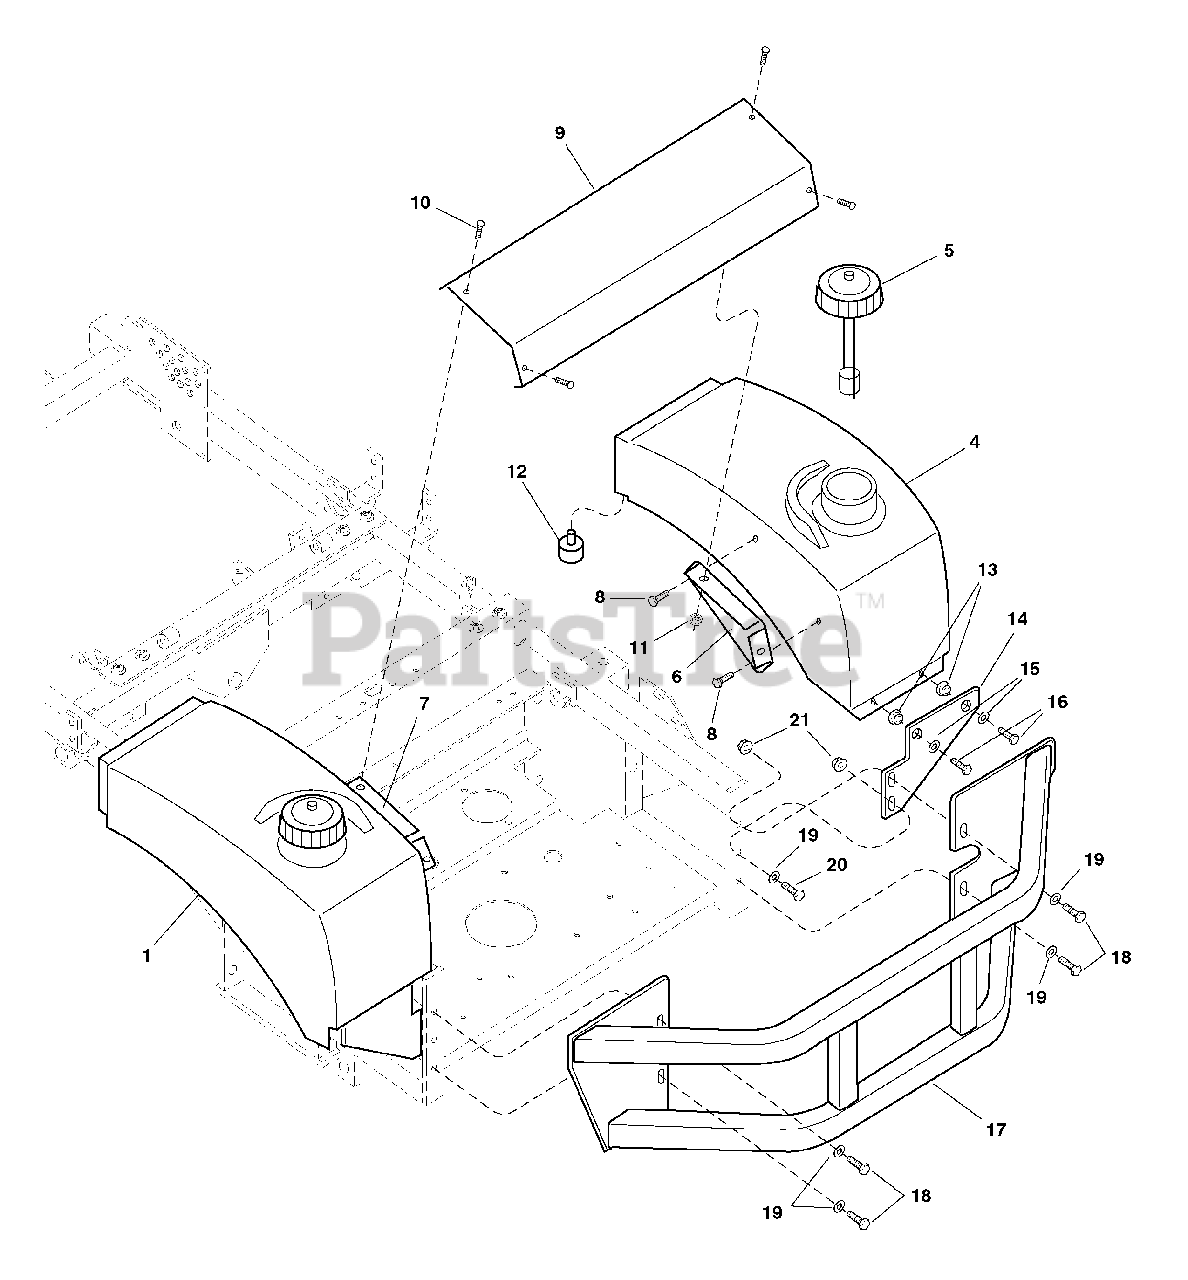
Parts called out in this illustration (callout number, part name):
1	FUEL TANK-LH, Complete (Includes Ref 2 & 3)
4	FUEL TANK-RH, Complete (Includes Ref 2 & 3)
5	CAP, w/ Gauge
6	TIE BAR MOUNT-RH
7	TIE BAR MOUNT-LH
8	CAPSCREW, Hex Hd, 5/16-18 x 3/4
9	FUEL TANK TIE BAR
10	SCREW, Torx Button Hd, 1/4-20 x 3/4
11	NUT, Hex, Nylon Lock, 1/4-20
12	RUBBER ISOLATOR
13	RUBBER BUSHING
14	FUEL TANK MOUNT PLATE
15	WASHER, 5/16
16	CAPSCREW, Hex Hd, 5/16-18 x 1-1/4
17	BUMPER
18	CAPSCREW, Hex Hd, 3/8-16 x 1-1/4
19	WASHER, 3/8
20	CAPSCREW, Hex Hd, 3/8-16 x 1
21	NUT, Hex, Serrated Flange, 3/8-16
